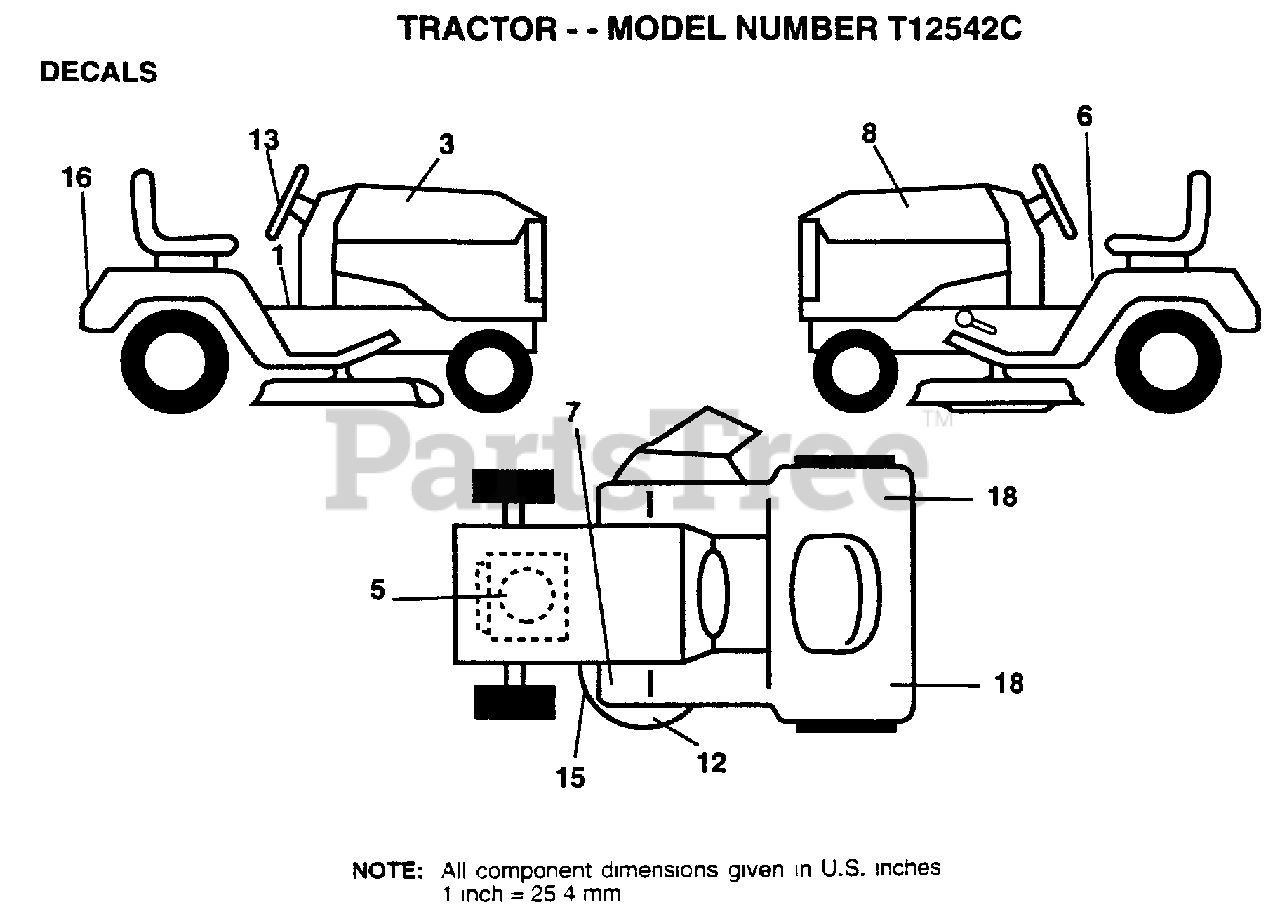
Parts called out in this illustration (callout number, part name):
3	DECAL.HD.RH.12.5
5	DECAL.ENG.272632
6	DECAL
8	DECAL.HD.LH.12.5
13	"DECAL,STR WHL T"
15	DECAL
16	DECAL.FENDER
18	REFLECTOR-TAIL YT
